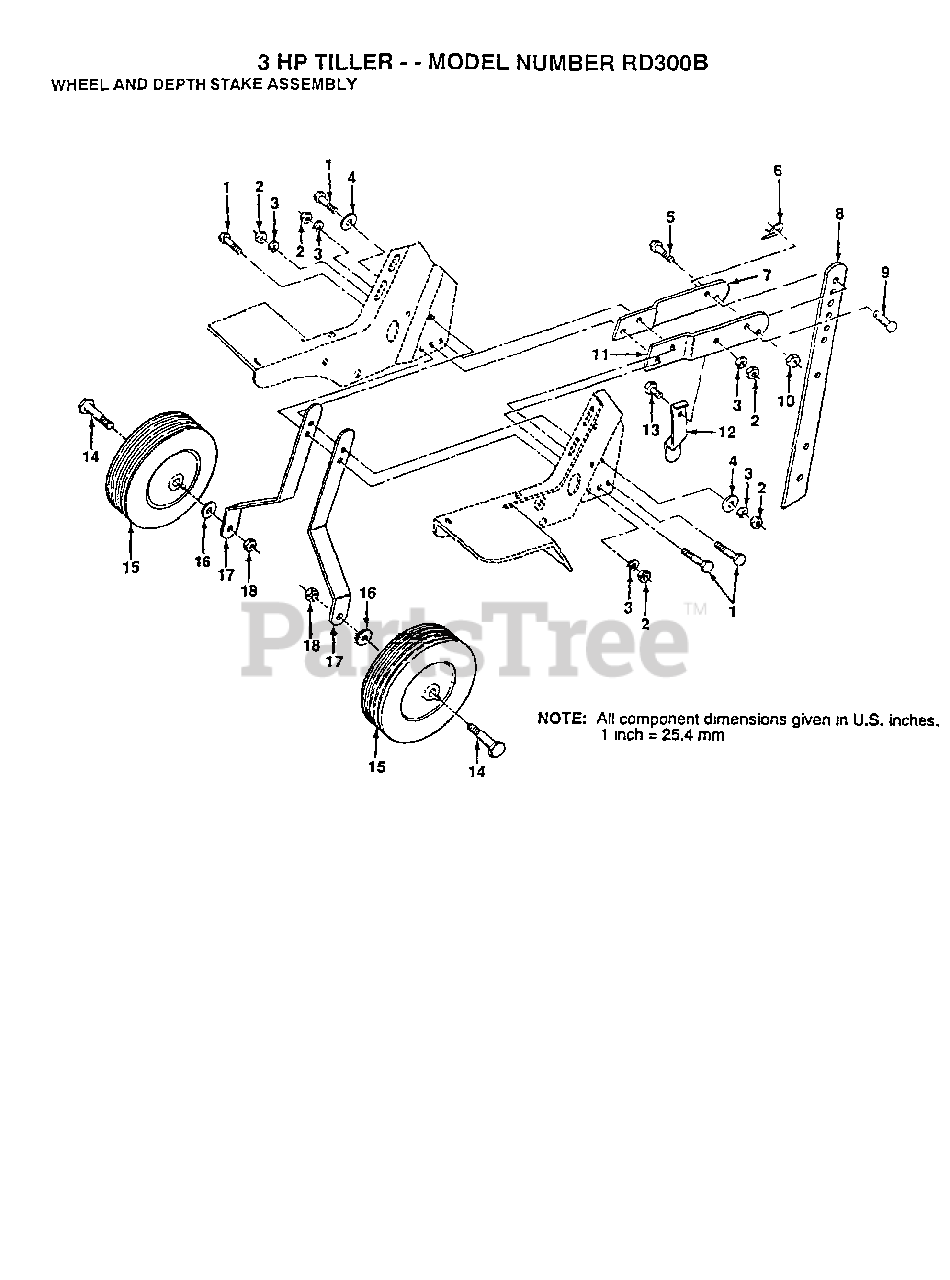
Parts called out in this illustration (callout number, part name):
2	NUT.HEX.5/16-18
3	LOCKWASHER
4	WASHER
5	BOLT.3/8-24X1-1/2
6	SPRING.RETAINER
7	STAKE.SUPT.TILLER
9	DRILLED RIVET RT
10	GRIPCO NUT
12	STAKE SPRING CT
13	BOLT
14	BOLT SHOULDER
16	WASHER
